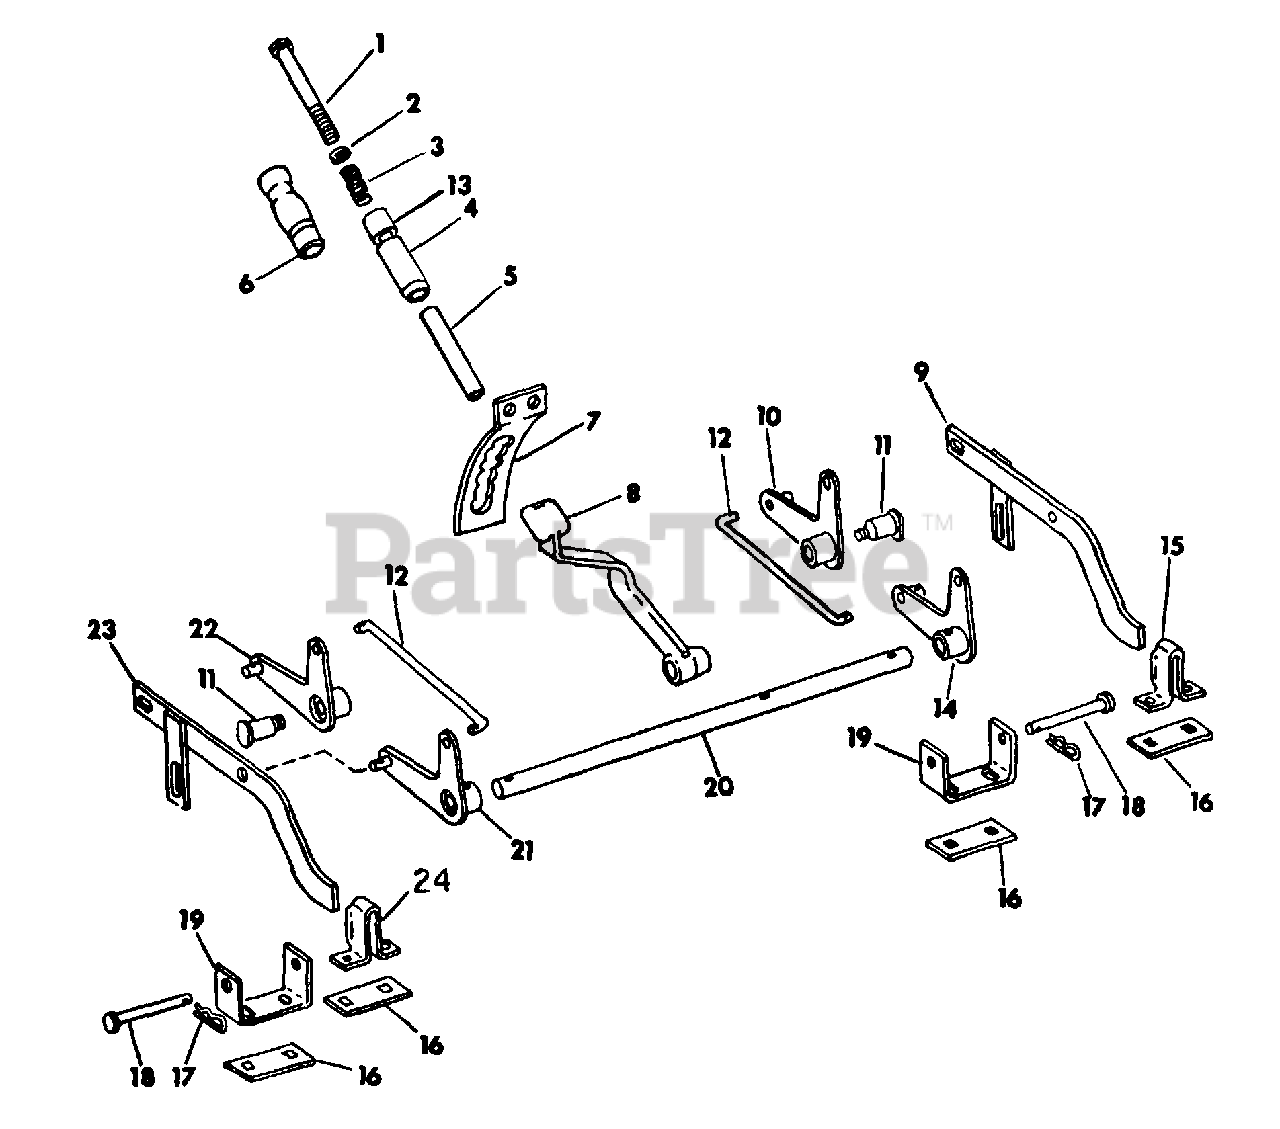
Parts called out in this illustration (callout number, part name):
1	SCREW, 3/8-16 X 6-1/4 ZND HEX-HD CAP
2	WASHER, SPRING RETAINING
3	SPRING, COMPRESSION
4	BUSHING, LIFT
5	BUSHING, LIFT HANDLE
6	GRIP, HANDLE
7	SECTOR LIFT HANDLE
9	SUPPORT ASSY, RH LIFT BAR
10	ARM ASSY. RH FRONT LIFT
12	ROD, CONNECTING LINK
13	BUSHING, LIFT HANDLE
14	ARM ASSY, RH REAR LIFT
15	CHANNEL, LIFT BAR REAR GUIDE
16	PLATE, STIFFENER
17	PIN, KLIK
19	CLEVIS, LOCK PIN FRONT BRACKET
21	ARM ASSY, LH REAR LIFT
22	ARM ASSY, LH FRONT LIFT
23	SUPPORT ASSY, LH LIFT BAR
24	CHANNEL, REAR GUIDE RH
